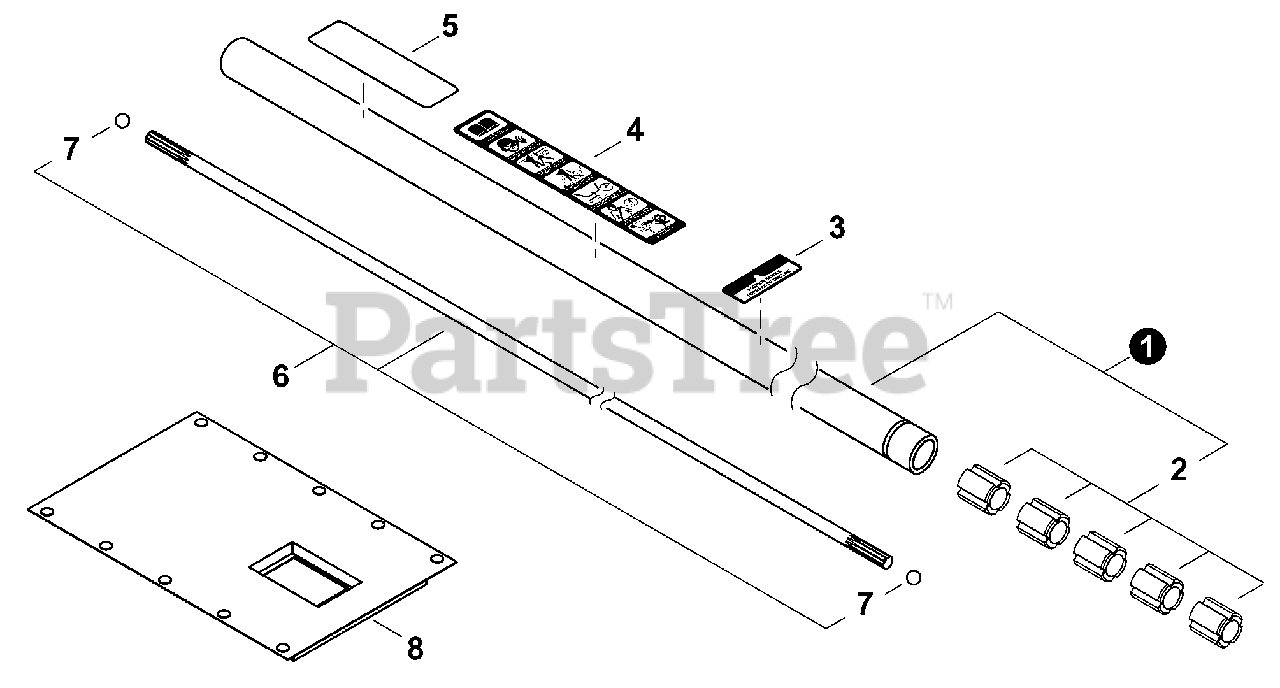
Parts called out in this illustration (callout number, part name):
1	MAIN PIPE ASSY
2	BUSHING
3	LABEL, HANDLE
4	LABEL, CAUTION (BLADE CAPABLE)
5	LABEL, shindaiwa PROFESSIONAL
6	SHAFT ASSY, DRIVE
7	STOPPER
8	PROTECTOR
